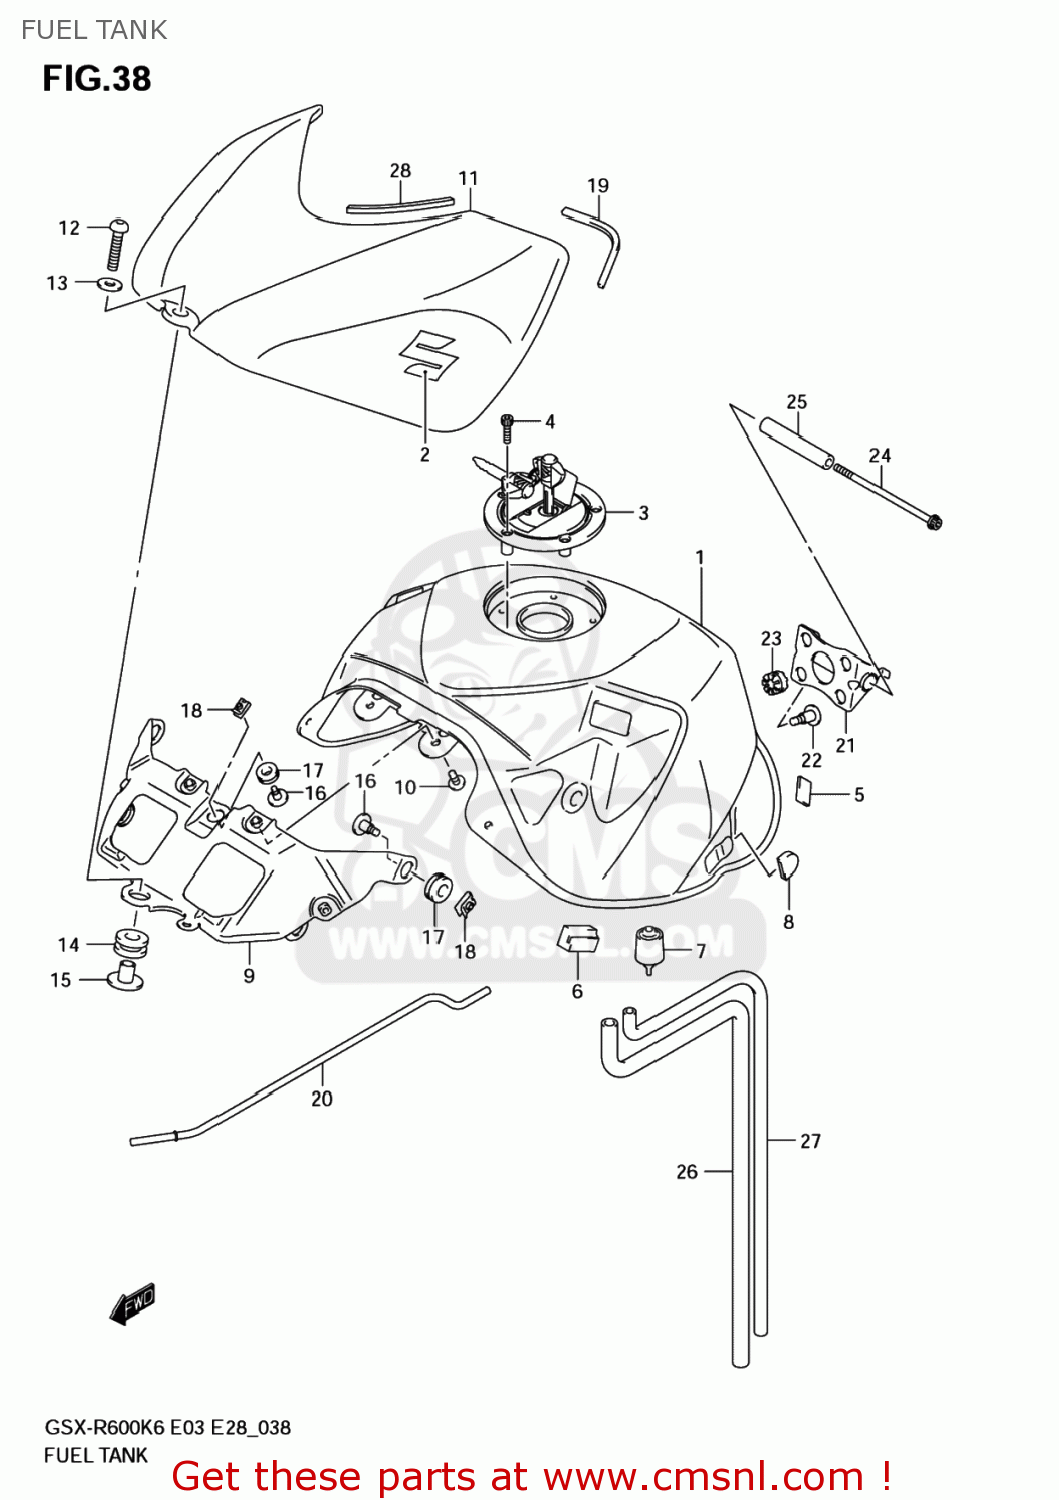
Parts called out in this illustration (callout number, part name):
1	TANK ASSY,FUEL(RED)
2	EMBLEM,S
3	CAP SET,FUEL TANK
4	BOLT(5X20)
5	FASTENER
6	CUSHION,FUEL TANK SIDE
7	CUSHION,FUEL TANK RR
8	CUSHION
9	BRACKET,FUEL TANK FR
10	SCREW(6X10)
11	COVER,FUEL TANK FR
12	BOLT(8X37)
13	WASHER(8.5X20X1.6)
14	CUSHION
15	SPACER (8.6X12
16	SCREW(5X16.4)
17	CUSHION
18	NUT
19	CUSHION,FUEL TANK COVER
20	STAY,FUEL TANK
21	BRACKET,FUEL TANK NO.1
22	SCREW,FUEL TAN
23	CUSHION
24	BOLT(6X110)
25	SPACER,FUEL TANK RR
26	HOSE,TANK WATER DRAIN
27	HOSE,TANK BREATHER
28	CUSHION,TANK COVER
